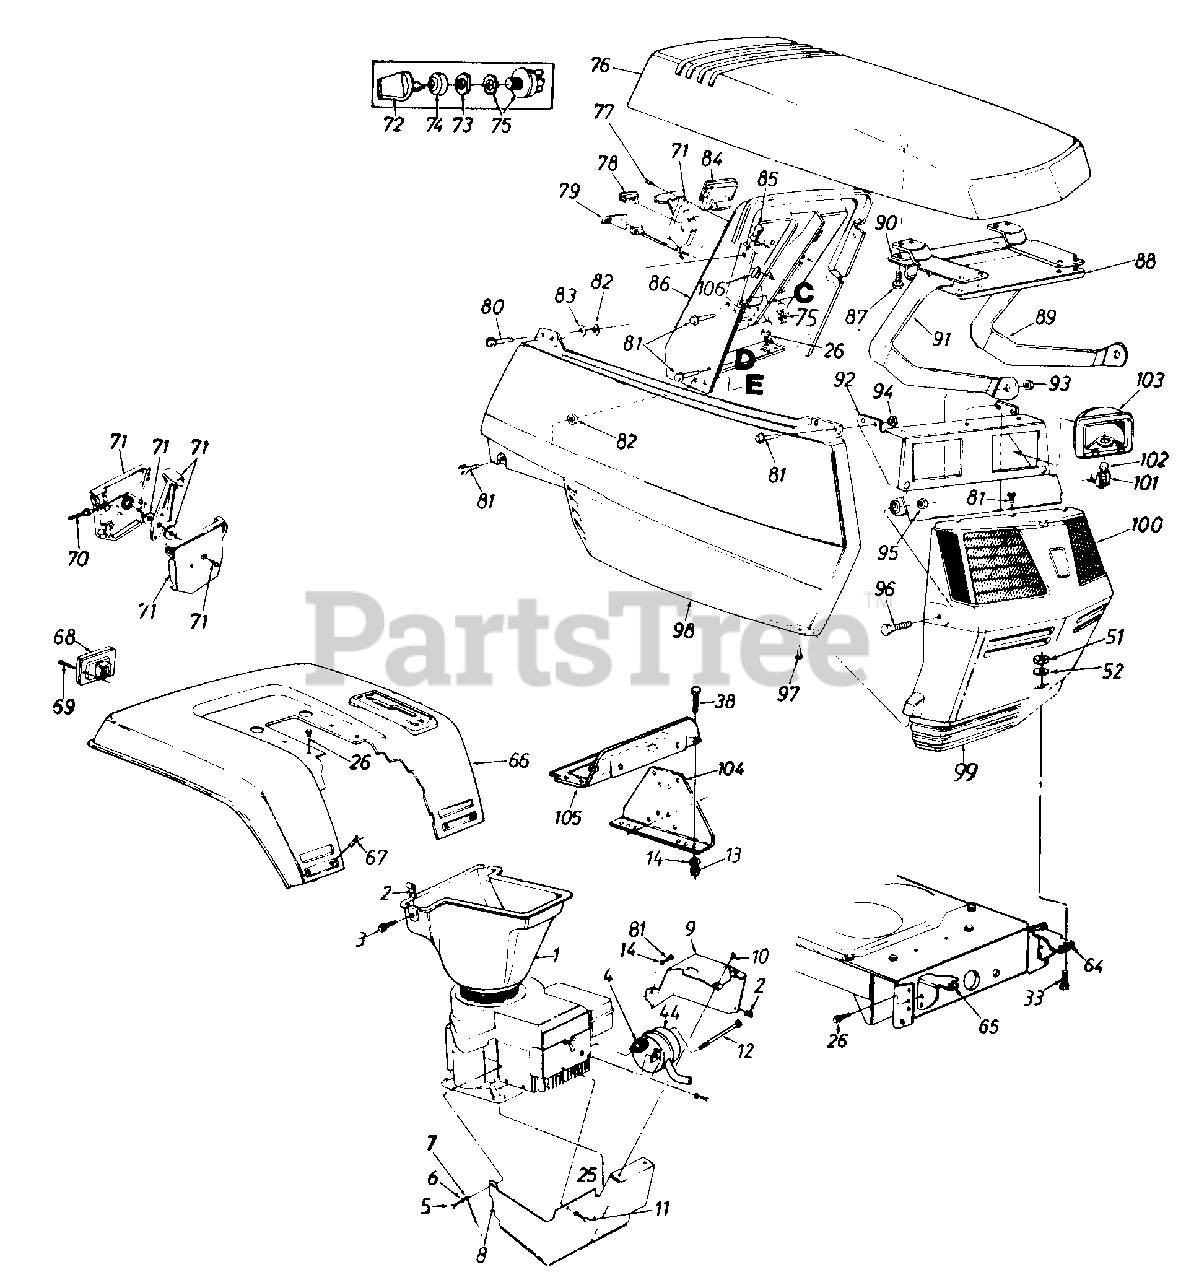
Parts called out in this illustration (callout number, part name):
1	Air Duct
2	Speed Nut #10-24 Thd.
3	Truss Mach. Scr. #10-24 x .5"
4	Gasket
5	Truss Mach. Scr. 5/16-18 x .75"
6	External L-Wash. 5/16" I.D.
7	Ground Wire
8	Muffler Heat Shield Front
9	Muffler Heat Shield L.H.
10	Hex Wash. Tap Scr. #10 x .5"
11	Hex Bolt i4-20 x 3/8" Lg.
12	Shld. Bolt 7116" Dia. x 3-518" Lg.
13	Hex Nut 1/4-20 Thd.
14	L-Wash. 1/4" I.D.
25	Spr. Wash. .265" I.D.
26	Hex Wash. Hd. AB-Tap Scr. 5/16 x .75" Lg.
33	Hex Bolt 5/16-18 x .75" Lg.
38	Hex Bolt 1/4-20 x .62" Lg.
44	Muffler
51	Hex Nut 5/16-18 Thd.
52	Fl-Wash. .343" I.D. x .687"
64	Grille Mount Brkt. L.H.
65	Grille Mount Brkt. R.H.
68	Taillight
69	Truss Hd. AB-Tap Scr. #6 x .62" Lg.
70	Throttle Wire 35" Lg.
71	Throttle Control Box Ass'y.
72	Ignition Key
73	Ignition Switch Nut
74	Ignition Switch Cap
75	Ignition Switch
78	Light Switch
79	Choke Control
80	Hex Wash. Hd. Tap Scr. 1/4 x.75" Lg.
81	Hex Tap Scr. 1/4-20 x .5" Lg.
82	Push Nut Fastener
83	Fl-Wash. .27" I.D. x .948"
84	Ammeter
85	Speed Nut 1/4-20 Thd.
86	Dash Panel
87	Hex Wash. Hd. B-Tap Scr. 1/4 x.62" Lg.
88	Hood Reinforcement
89	Hood Hinge L.H.
94	Hex L-Nut 1/4-20 Thd.
95	Hex Jam Nut 5/16-18 Thd.
96	Hex Bolt 5/16-18 x 718" Lg.
97	Truss Mach. B-Tap Scr. #10 x .5" Lg.
98	Side Cover R.H.
99	Grille
100	Lens L.H.
101	Twist Lock Lamp Socket
102	Lamp
103	Headlight Housing
106	Choke Retainer
